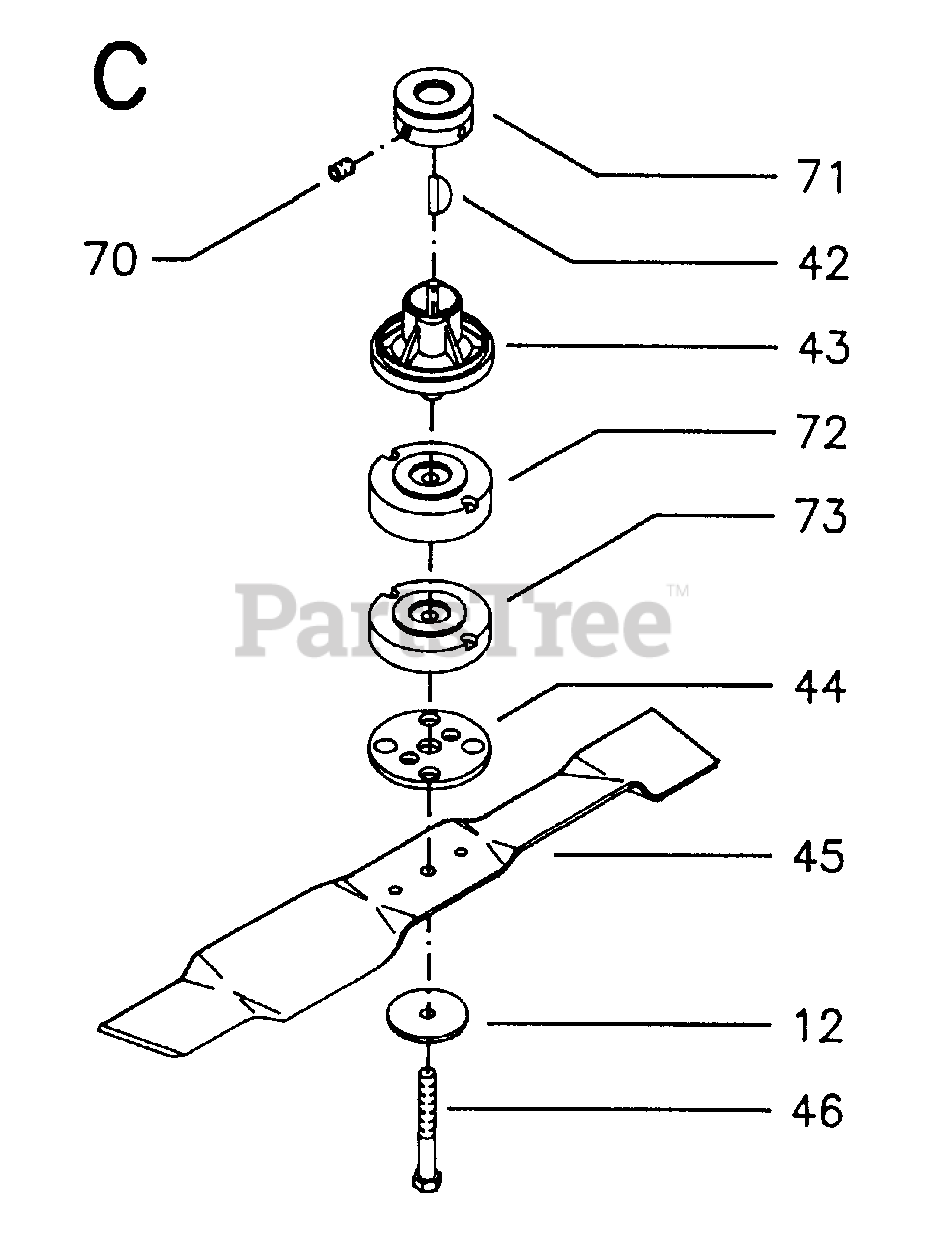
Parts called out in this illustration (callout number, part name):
42	WOODRUFF KEY
43	BLADE ADAPTER
44	STEEL PLATE ADAPTER
45	BLADE
72	SPACER
73	SPACER
